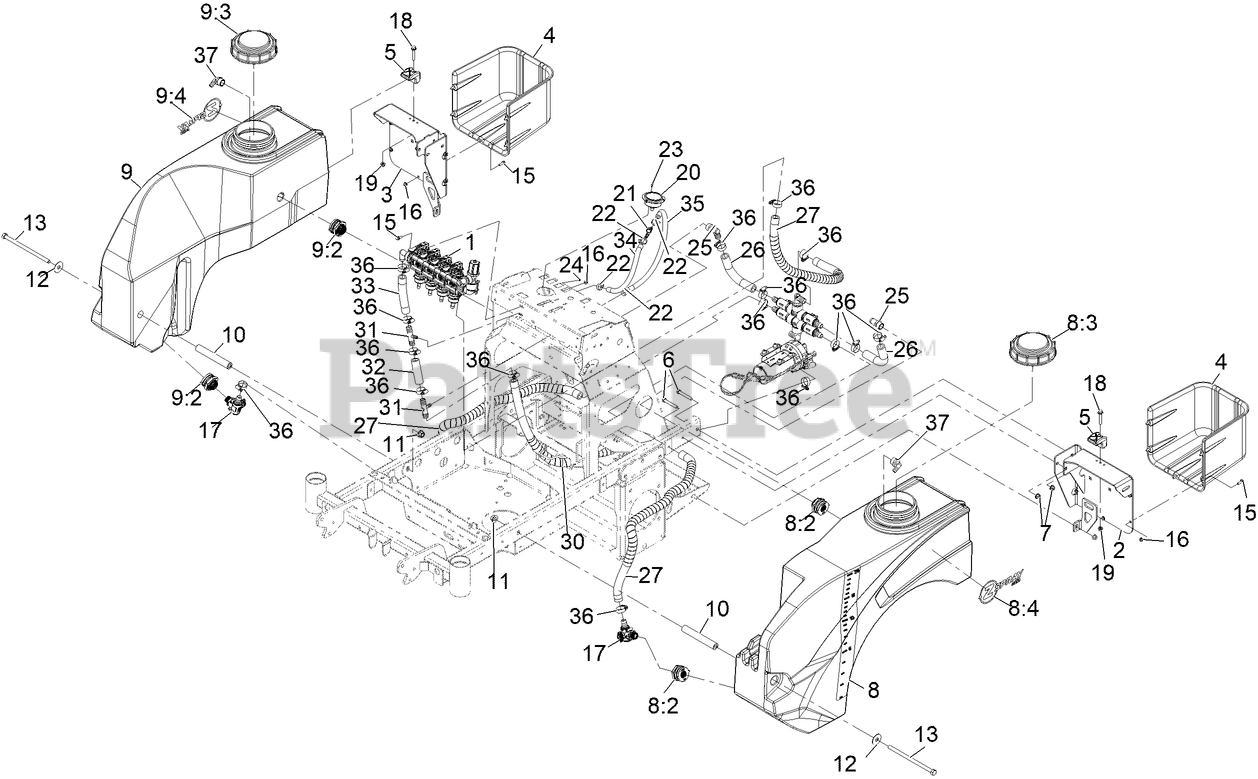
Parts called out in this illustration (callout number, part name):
1	ASM-MANIFOLD, SPRAY
2	MOUNT-TANK, LT INT
3	MOUNT-TANK, RT INT
4	BOX-FERTILZER, MID
6	HHCS,3/8-16X2-1/2,ST/ST 18-8
7	Nut-Hex Flange
8	TANK-20GAL, LT
8:2	FITTING-BULKHEAD
8:3	CAP-TANK, SPRAY
8:4	DECAL-Z-SPRAY MID LOGO
9	TANK-20GAL, RT
9:2	FITTING-BULKHEAD
9:3	CAP-TANK, SPRAY
9:4	DECAL-Z-SPRAY MID LOGO
10	SPACER-TANK
11	NUT-HEX FLANGE
12	WASHER-FLAT, 1/2, SS
13	SCREW-HHCS
15	Screw-HHF
16	Nut-Hex Flange
17	VALVE-3 WAY
18	SCREW-HHF
19	Nut-Hex Flange
20	GAUGE-PRESSURE
21	FITTING-TEE
22	CLAMP-HOSE
23	SCR,MCH,6-32X3/8,PHPH,SST,ROHS
24	NUT-HEX
25	FITTING-ELBOW, 90
26	HOSE-SPRAY, FORMED
27	HOSE-SPRAY, WRAPPED
30	HOSE-SPRAY, WRAPPED
31	TEE-HOSE BARB
32	HOSE-SPRAY
33	HOSE-SPRAY
34	HOSE-SPRAY
35	HOSE-SPRAY
36	CLAMP-HOSE
37	FITTING-ELBOW, 90
